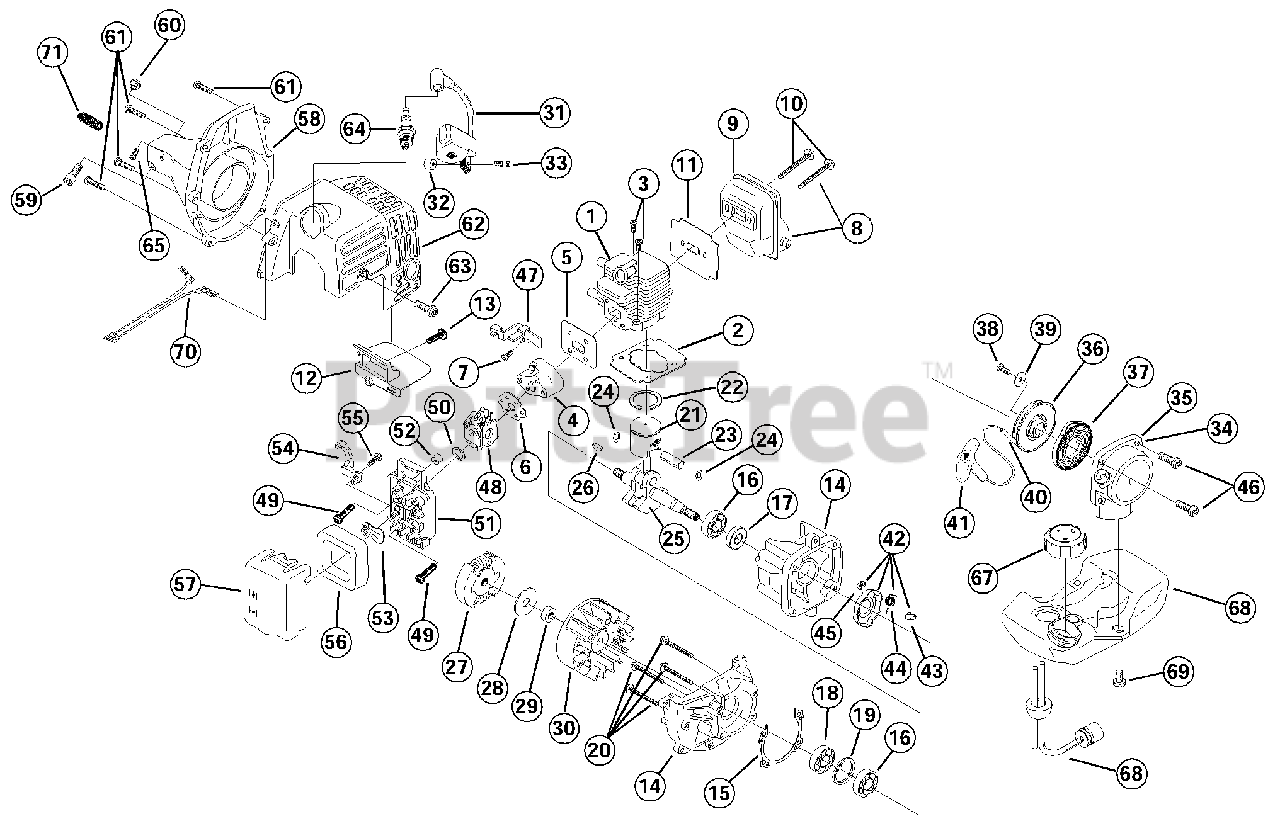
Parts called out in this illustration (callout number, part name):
1	Cylinder
2	Cylinder Base Gasket
4	Insulator
5	Insulator Gasket
6	Carburetor Gasket
8	Muffler Assembly
9	Muffler
11	Muffler Gasket
12	Muffler Plate
14	Crankcase Service Assembly
15	Crankcase Gasket
16	Bearing
17	Oil Seal
18	Oil Seal
19	Snap Ring
23	Piston Pin
24	Snap Ring
25	Crankshaft
27	Clutch Rotor
28	Clutch Washer
30	Flywheel Assembly
31	Module Assembly
33	Screw
34	Recoil Assembly
35	Recoil Case
36	Recoil Pulley
37	Recoil Spring
41	Pull Handle
42	Pulley Assembly
43	Ratchet
45	Retaining Ring
47	Throttle Bracket
48	Carburetor
51	Air Cleaner Assembly
53	Choke Plate
54	Choke Lever
56	Air Filter
57	Air Cleaner Cover
58	Clutch Housing Assembly
59	Engine Bolt
62	Engine Cover
64	Spark Plug
65	Anti-Rotation Screw
66	Fuel Tank
67	Fuel Cap Assembly
68	Fuel Line Assembly
70	Lead Wire Assemby
71	Compression Spring
